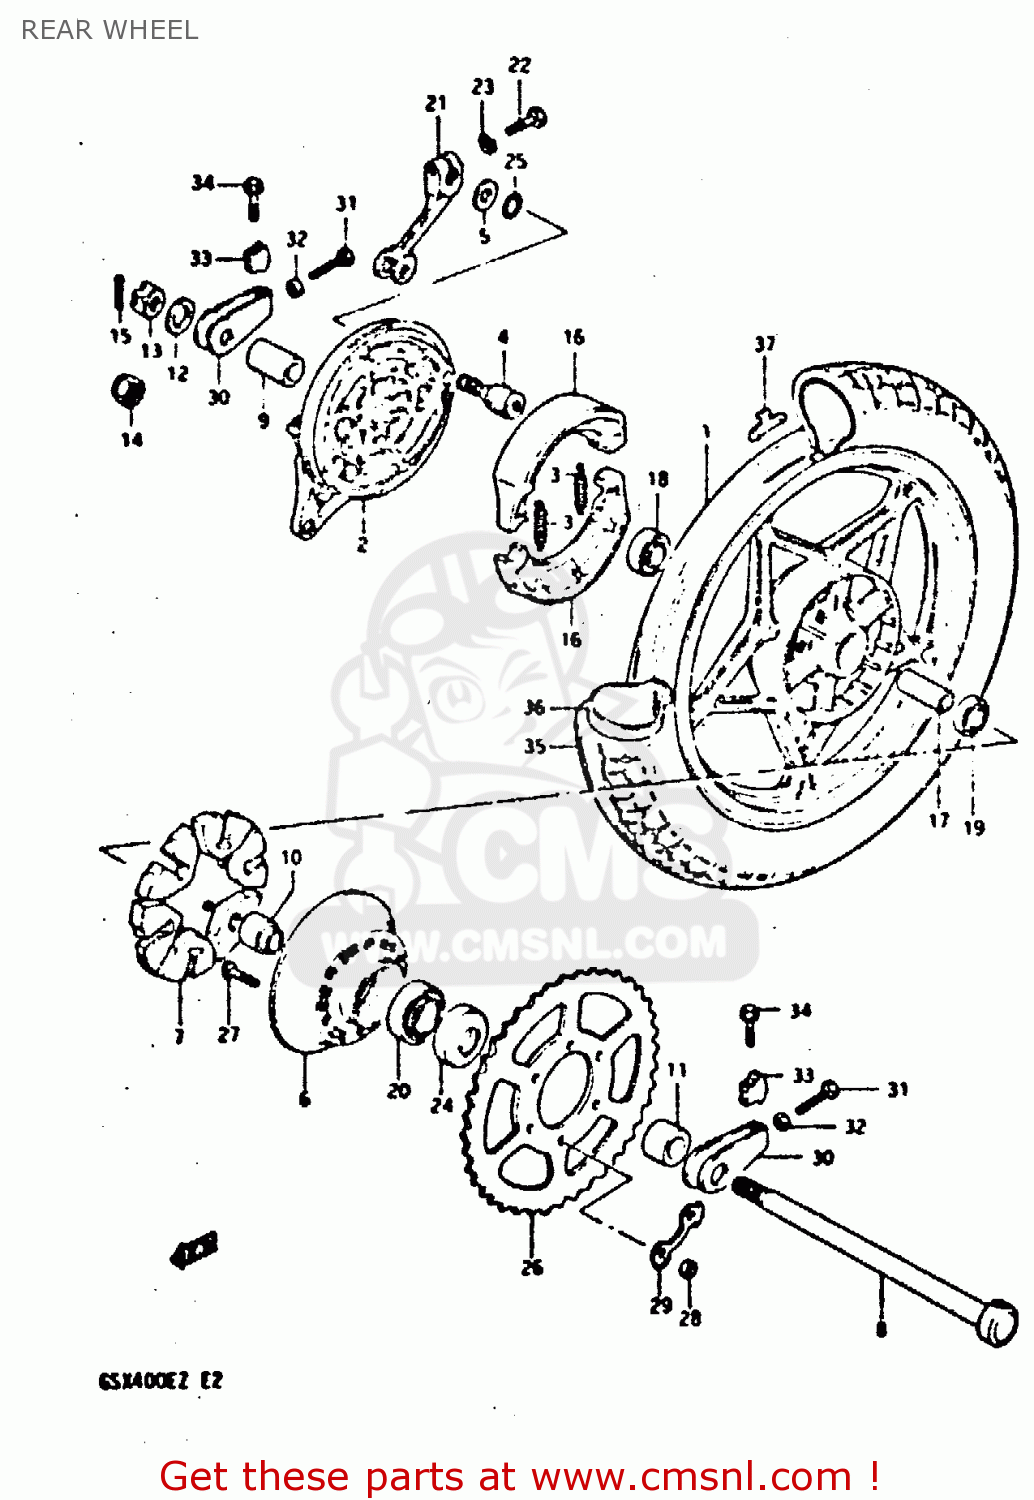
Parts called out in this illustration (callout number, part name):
1	CASTING WHEEL,REAR 1.85-
2	PANEL,REAR HUB
3	SPRING,BRAKE SHOE
4	CAM,FRONT BRAKE
5	WASHER (15X24X1.6)
6	DRUM,REAR SPROCKET MOUNT
7	ABSORBER,RR HUB SHOCK
8	AXLE,REAR
9	SPACER(17.5X28X44.8)
10	SPACER,REAR HUB BEARING
11	SPACER(17X30.5X22.3)
12	WASHER (17X30X3.2)
13	NUT
15	PIN,COTTER
16	SHOE,BRAKE
17	SPACER (17.6X24X57)
18	BEARING
19	BEARING
20	BEARING
21	LEVER,RR BRAKE CAM
22	BOLT
23	LOCK WASHER
24	SEAL,OIL(30.5X52X8)
25	O-RING,BOSS
26	SPROCKET,RR
27	BOLT
28	NUT
29	WASHER
30	ADJUSTER,CHAIN
31	BOLT 8X50
32	NUT
33	SUPPORTER,CHAIN ADJUST
34	BOLT
35	TIRE
36	TUBE ASSEMBLY,WHEEL,INNER
37	BALANCER,WHEEL
